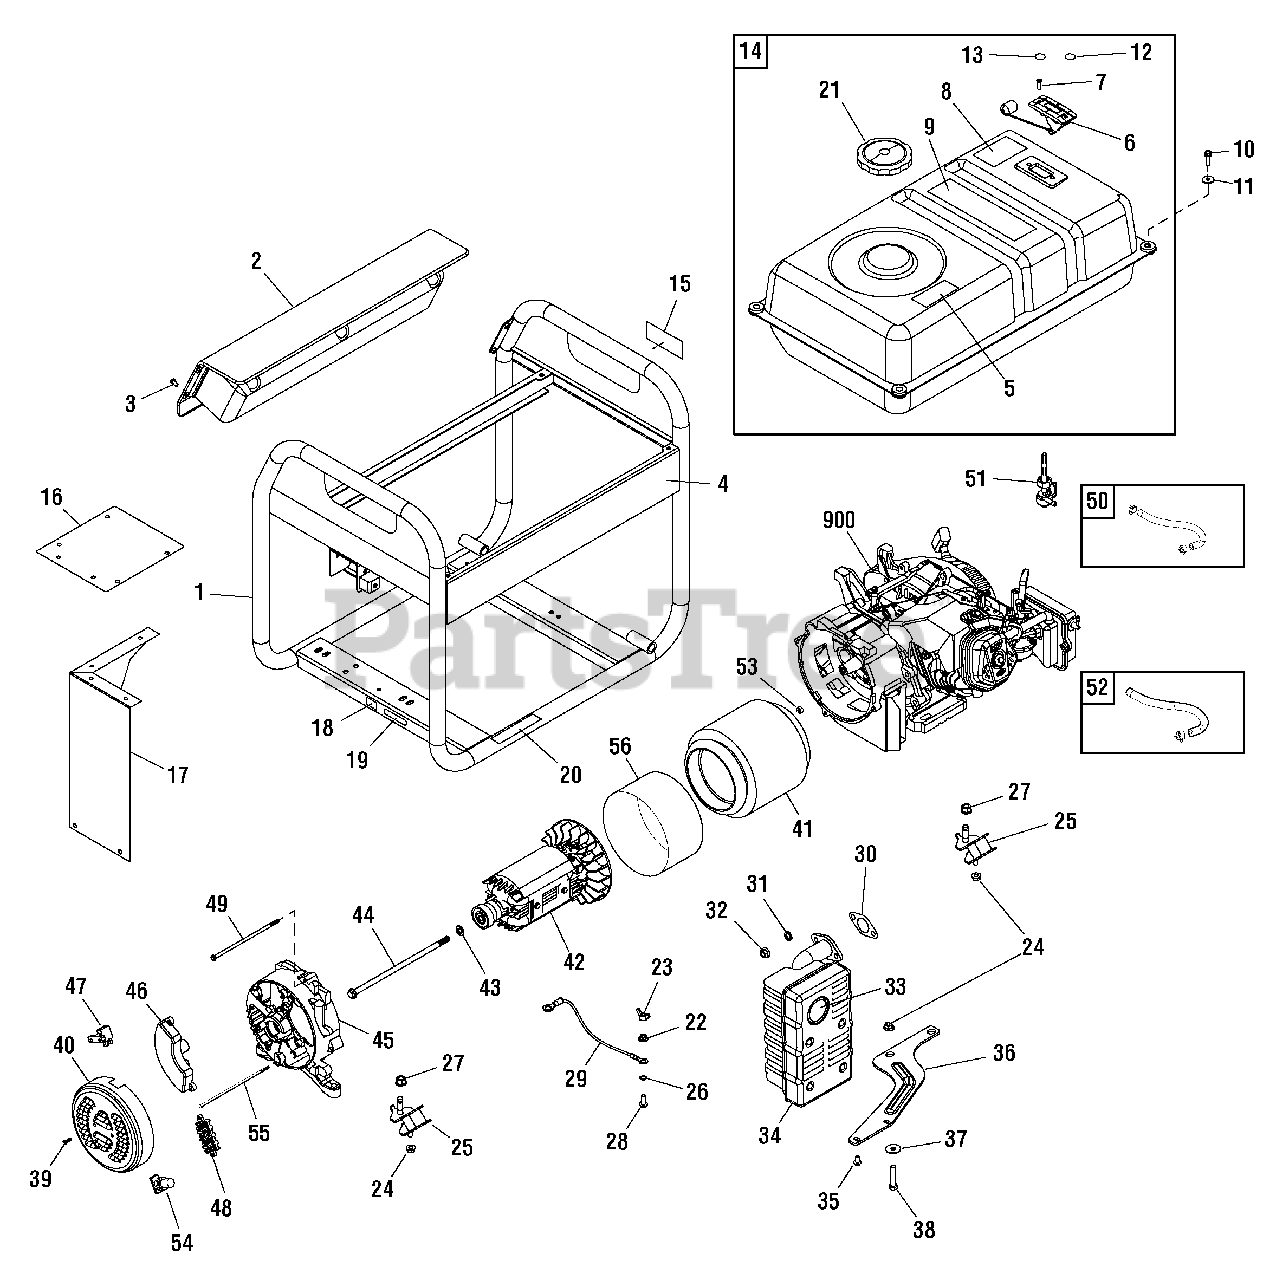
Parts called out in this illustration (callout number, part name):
22	* NUT, Flange Lock, M6
24	* NUT, Flange Lock, M8
25	MOUNT-VIBRATION
26	* WASHER, Shakeproof, Ext M6
27	* NUT, Flange Lock, M10
28	* SCREW, Flange, M6 x 16
30	GASKET
31	* WASHER, Lock, M8
32	* NUT, Hex, M8-1.25
35	* SCREW, Flange, M6 x 12
36	BRACKET, Muffler
37	* WASHER, Flat M8
38	CAPSCREW, Hex Head, M8-1.25 x 40
45	CARRIER-BEARING
46	VOLTAGE REGULATOR
50	KIT-FUEL HOSE
900	** ENGINE
